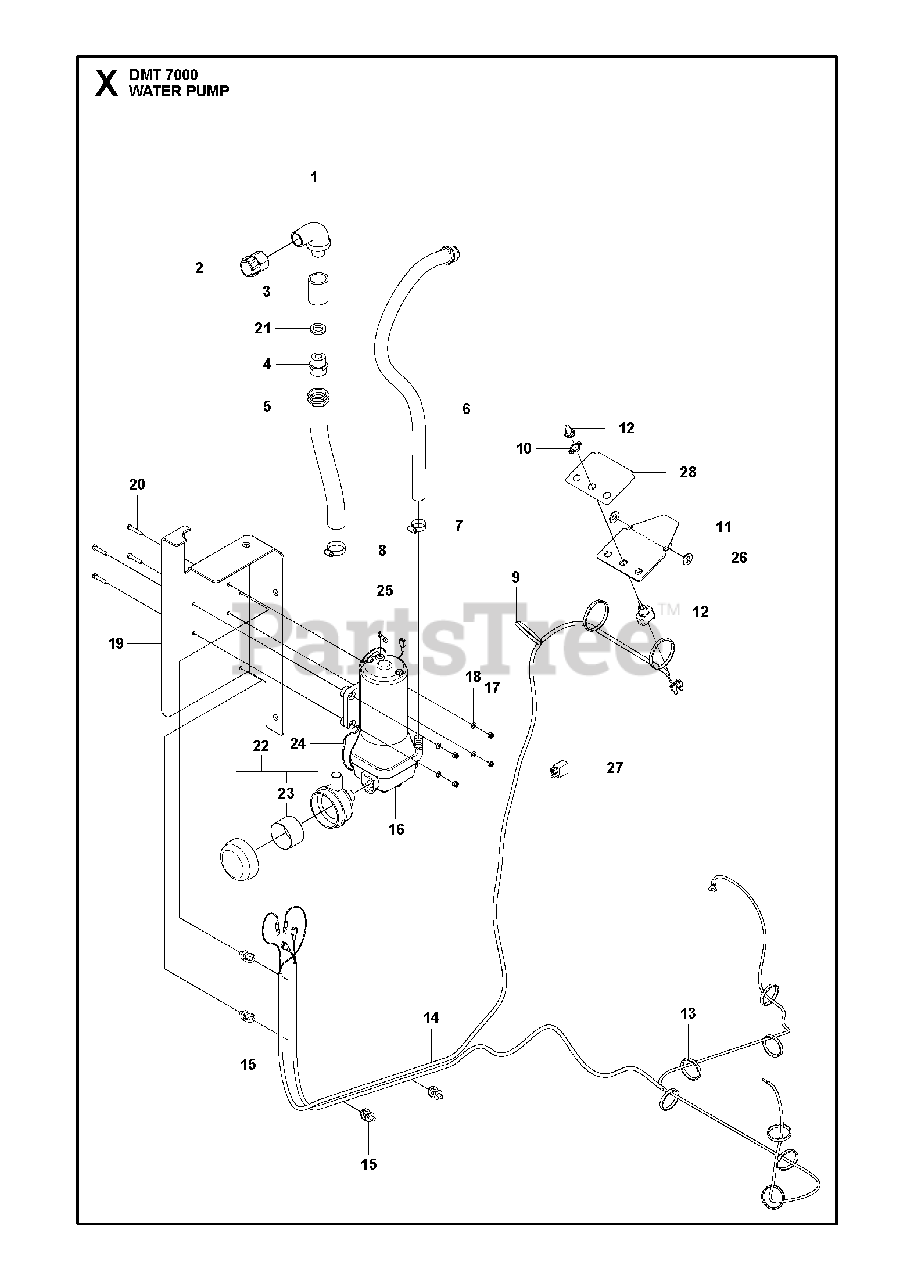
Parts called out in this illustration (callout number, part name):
17	HEXAGON LOCKING NUT
18	WASHER
23	STRAINER SCREEN. W/P INLET FILTER
25	TERM., MALE DISCONNECT, 1/4"
26	WASHER
